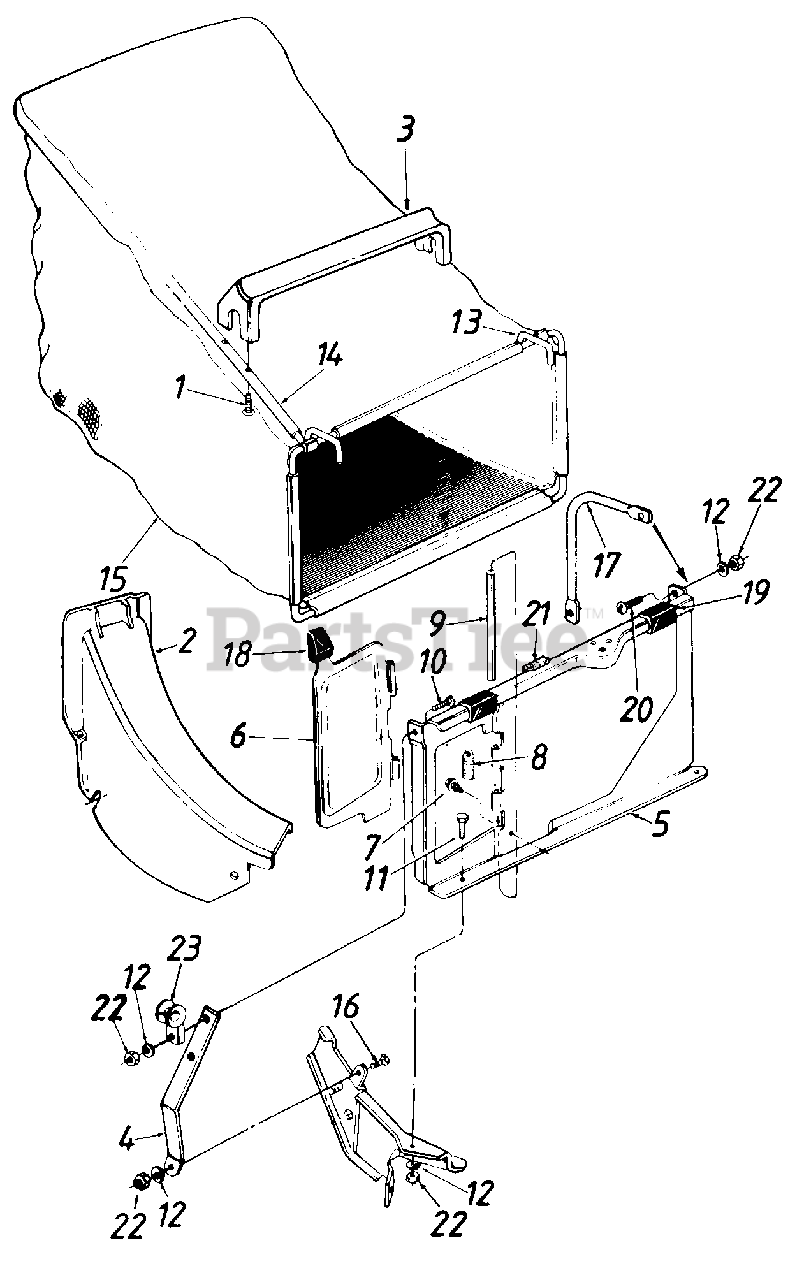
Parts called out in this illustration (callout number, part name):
1	Hex AB-Tap Scr. #12 x 1.25" Lg.
2	Rear Discharge Chute Ass'y.
3	Bag Handle
7	Hex B-Tap Scr. #10 x .38"
8	Torsion Spring
9	Pivot Pin
10	Truss Mach. Scr. 1/4-20 x 3/4" Lg.
11	Hex Bolt 1/4-20 x .50" Lg.*
12	L-Wash. 1/4" I.D.*
15	21" Rear Discharge Grass Bag
16	Hex Bolt 1/4-20 x .62" Lg.
17	Catcher Panel Support Arm
18	Door Grip
19	Panel Clip
20	Truss Mach. Scr. 1/4-20 x .62" Lg.
21	Foam Strip
22	Hex Nut 1/4-20 Thd.*
23	Rope Guide
